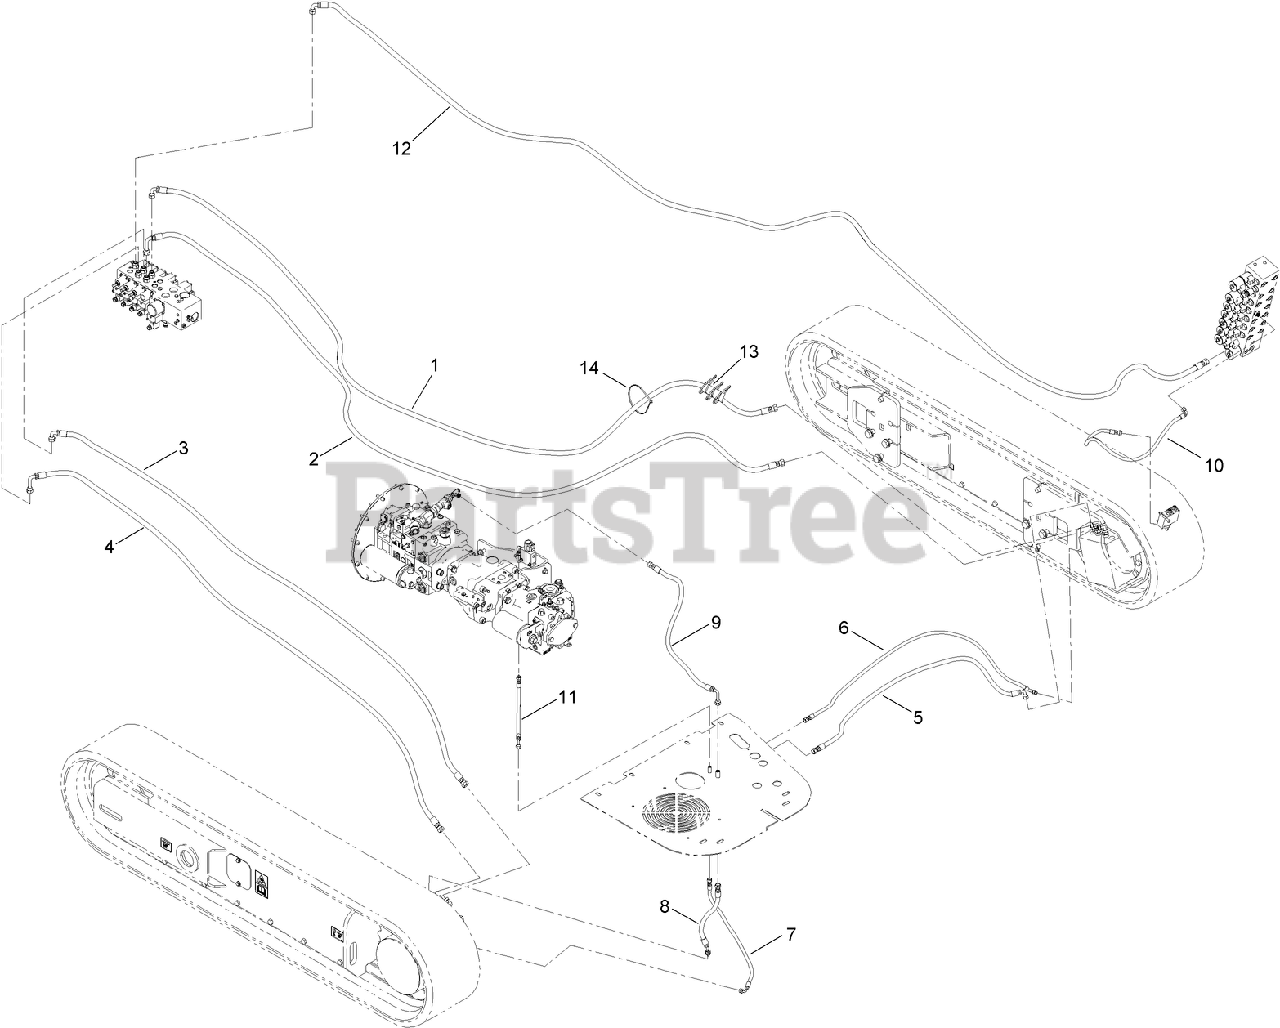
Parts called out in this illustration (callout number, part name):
1	HOSE ASM-HYD
2	HOSE ASM-HYD
3	HOSE ASM-HYD
4	HOSE ASM-HYD
5	HOSE ASM-HYD
6	HOSE ASM-HYD
7	HOSE ASM-HYD
8	HOSE ASM-HYD
9	HOSE ASM-HYD
10	HOSE ASM-HYD
11	HOSE ASM-HYD
12	HOSE ASM-HYD
13	PROTECTOR-HOSE
14	TIE-CABLE
